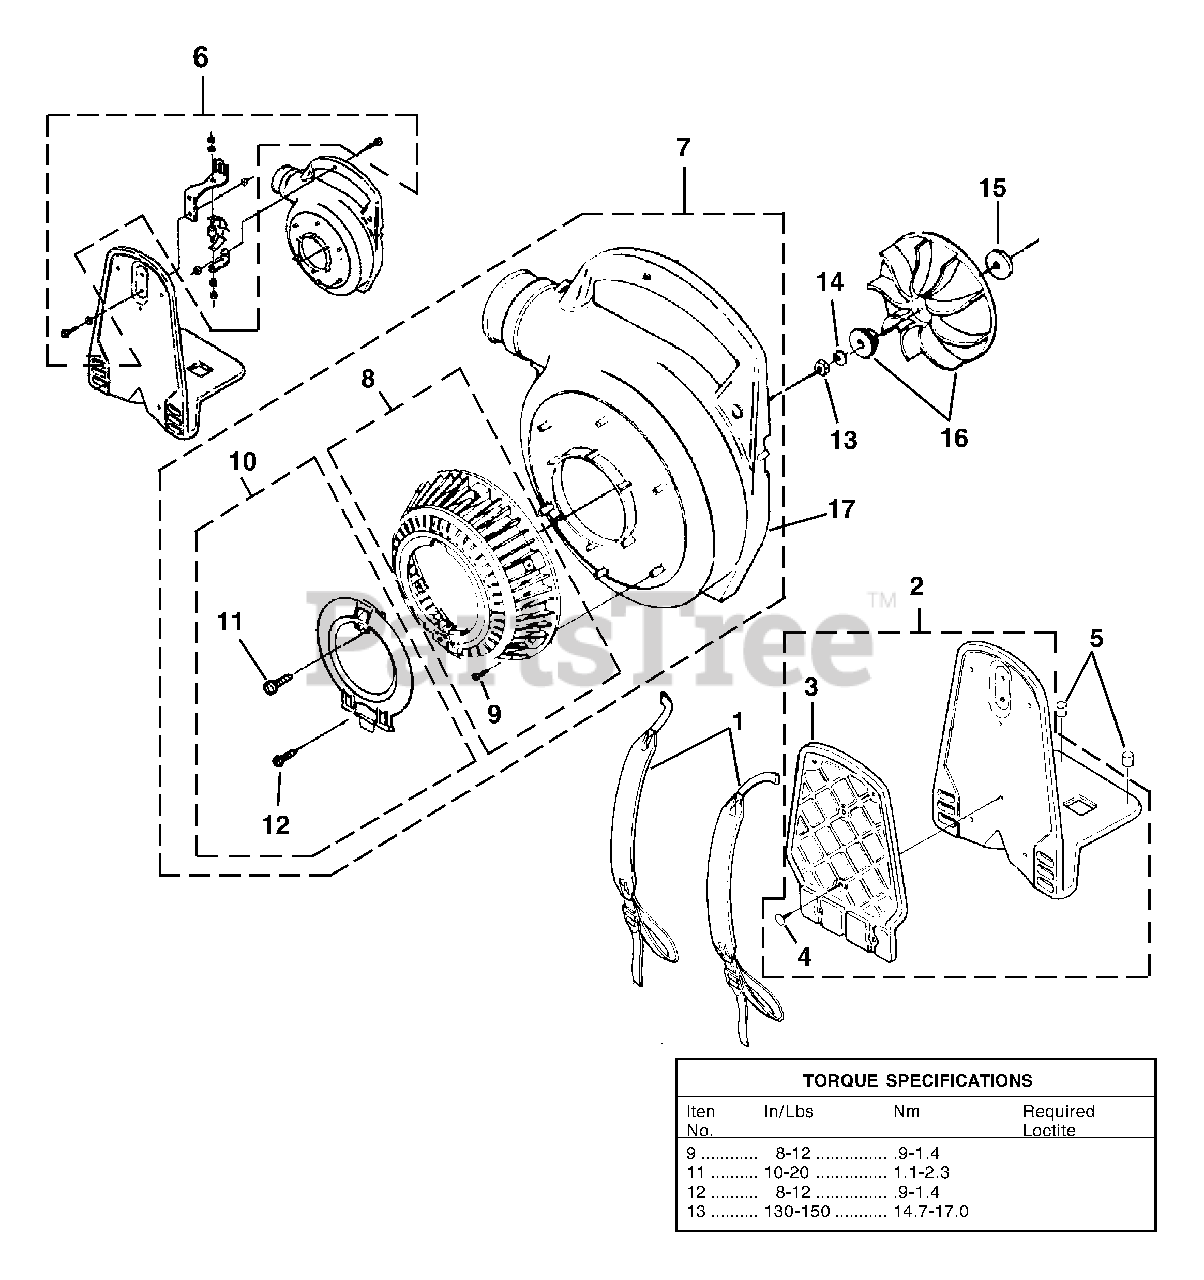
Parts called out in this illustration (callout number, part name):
1	HARNESS-Shoulder
2	FRAME-Blower
3	PAD-Foam
4	CLIP-Push
5	VIBRATION ISOLATOR
6	VIBRATION ISOLATOR KIT
7	VOLUTE HOUSING KIT
8	BLOWER VAC GRILLE KIT
9	SCREW-Thread Form. (#6 X 3/8")
10	ACCESS DOOR KIT **
11	SCREW-Thread Rolling (#10 X 5/8")
12	SCREW-Thread Form. (#8 X 1/2")
13	NUT-Hex (3/8-24)
14	WASHER-Bellville (3/8")
15	WASHER-Flat
16	BLOWER FAN KIT
17	VOLUTE OUTER - SVC
